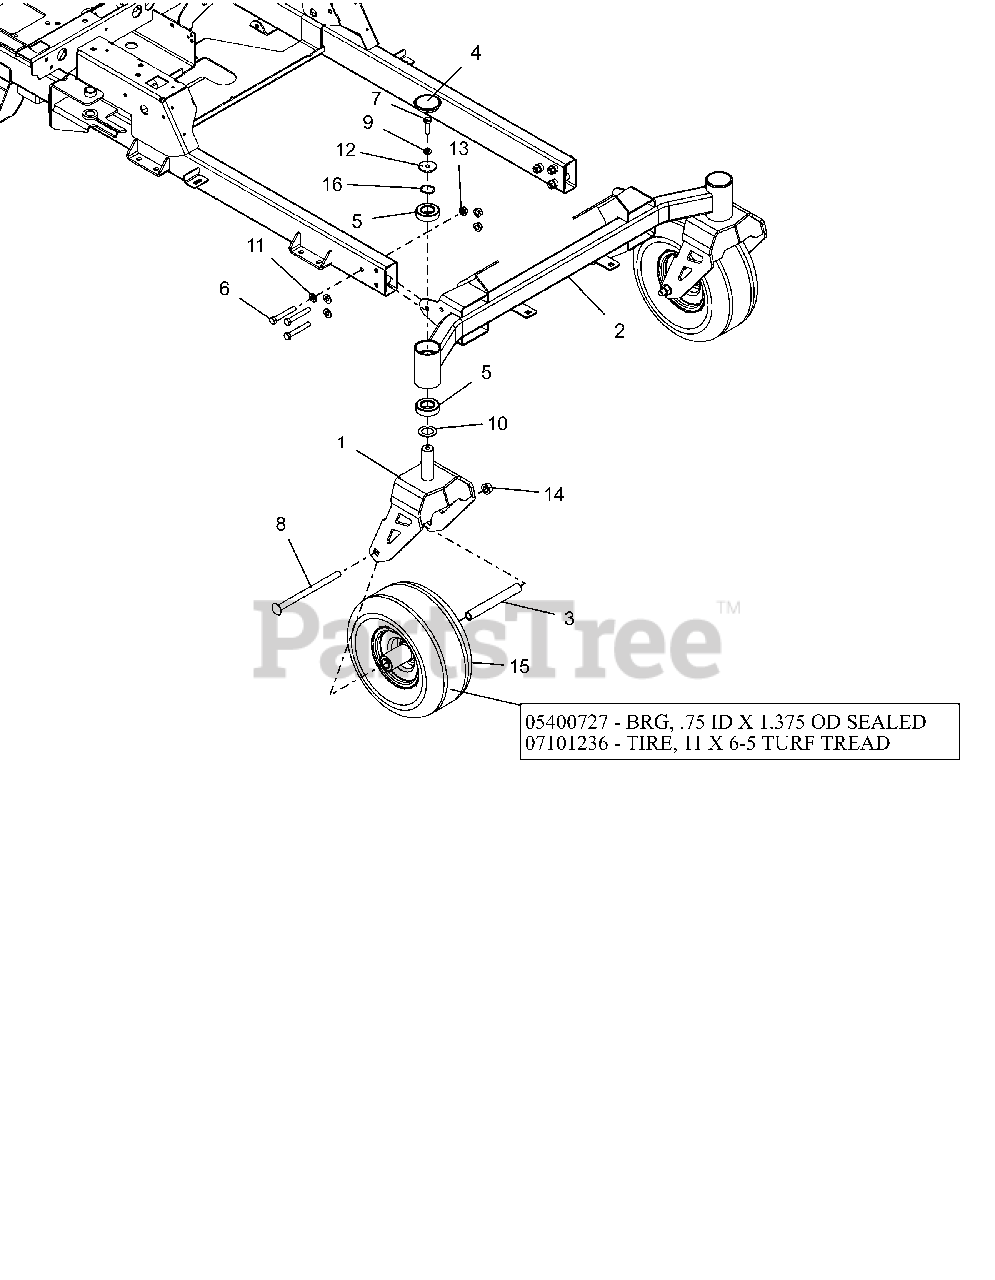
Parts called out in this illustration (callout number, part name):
1	WLDMT, CASTER FORK (WIDE)
2	WLDMT, AXLE FRONT
3	SPACER, FRONT WHEEL (WIDE 6.0)
4	CAP, DUST
5	BRG,BALL 1.00X2.00X.563(1641)
6	BLT-HEX .38-16X2.50 GR8 YWZC
7	@BLT-HEX .38-16X1.25 GR5 YWZC
8	@BLT-RDHDSQNK .50-13X7.50 G5YZ
9	@WSHR-LK .38X.094 REG YWZC
10	WSHR-HRD-THRS 1.007X1.542X.062
11	WSHR-HDND .406X.812X.055
12	WSHR-FL-STL .380X1.50X.125YWZC
13	NUT-LK-TOP-FLG .38-16 GRG YWZC
14	@NUT-LK-TOP-FLG .50-13 YWZC
15	TIRE/WHEEL ASSY, 11X6-5
15	BRG, .75 ID X 1.375 OD SEALED
15	TIRE, 11X6-5 TURF TREAD
16	WSHR-WAVE 1.0X1.25X.028 .145FH
